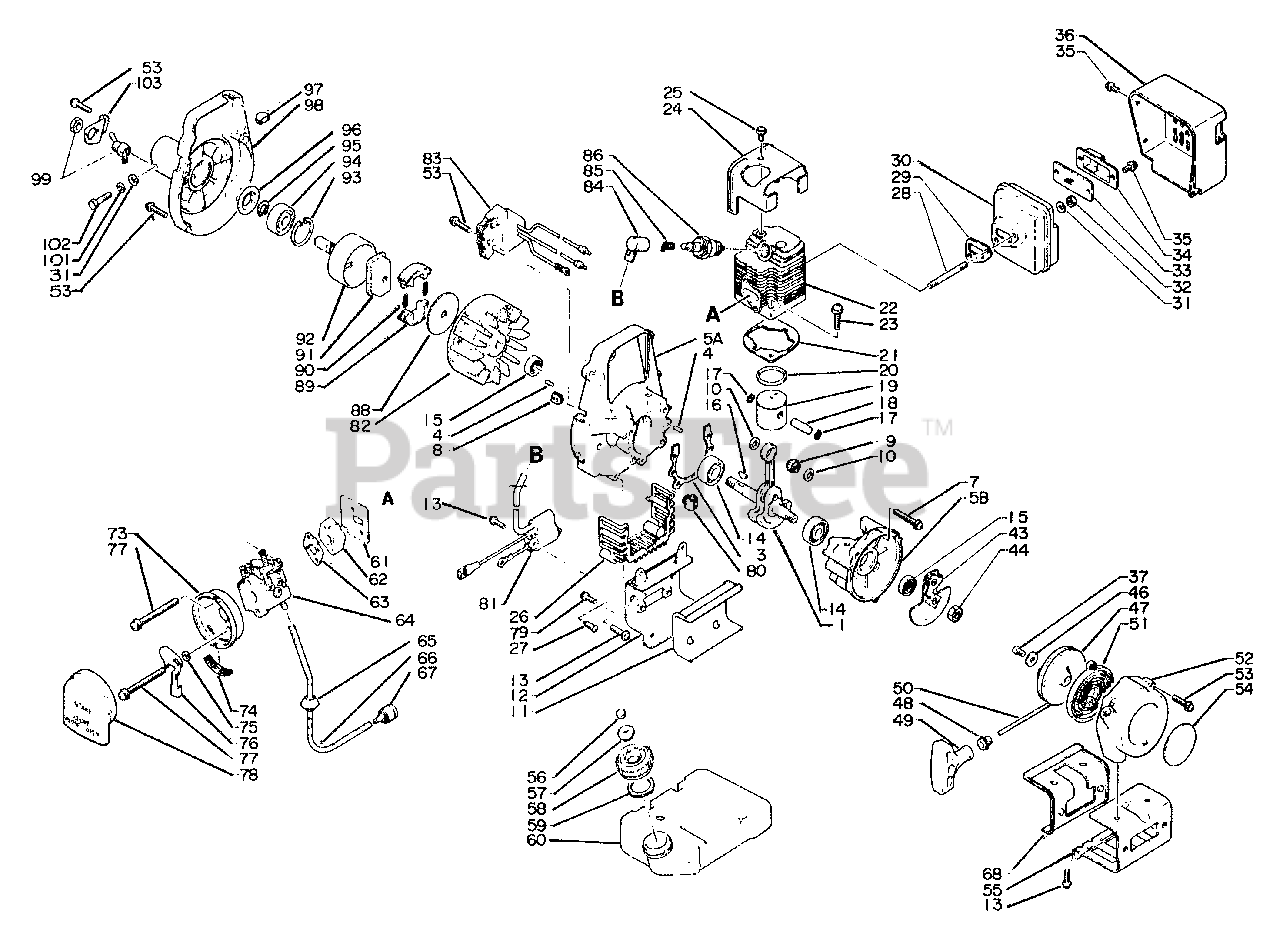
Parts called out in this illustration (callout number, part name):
1	CRANKSHAFT ASSY
3	GASKET, CRANKCASE
4	PIN - LOCATING
5	CRANKCASE KIT
5A	CRANKCASE KIT
5B	CRANKCASE KIT
7	SCREW - 5X30
9	BEARING, NEEDLE - 8
10	SPACER, PISTON
11	CUSHION
12	BRACKET, FUEL TANK
13	SCREW - 4X14
14	BEARING, BALL - 6201
15	SEAL, OIL
17	RING, RETAINING
18	PIN, PISTON
19	PISTON
20	RING, PISTON
21	GASKET, CYLINDER
22	CYLINDER
23	SCREW - 6X20
24	COVER, ENGINE
25	SCREW - 5X10
26	SEAL, DUST
27	SCREW - 4X14 -- TAPPING
29	GASKET, EXHAUST
30	MUFFLER
31	WASHER - 5
32	LOCKNUT - 5
33	SCREEN, SPARK ARRESTOR
34	GUIDE, EXHAUST
35	SCREW - 4X10
36	COVER, MUFFLER
37	SCREW - 4X10
43	STARTER PAWL ASSY
44	STARTER ASSY
46	WASHER
47	REEL, ROPE
48	ROPE, STARTER - 3X850
49	GRIP, STARTER
50	GUIDE, ROPE
51	SPRING, REWIND
52	CASE, STARTER
53	SCREW - 4X20
54	LABEL - ECHO
55	BRACKET, FUEL TANK
58	CAP
59	GASKET, CAP
60	TANK, FUEL
61	GASKET, INTAKE
62	INSULATOR, INTAKE
63	GASKET, INTAKE
64	CARBURETOR WA-81
66	PIPE - 3X5X150 -- BLACK
67	FILTER, FUEL
68	CUSHION
73	CASE, AIR FILTER
75	WASHER - 5
76	SHUTTER, CHOKE
77	SCREW - 5X57
78	FILTER, AIR
79	SCREW - 4X12
80	CLAMP
81	COIL, IGNITION
82	FLYWHEEL
83	COIL, IGNITION
84	CAP, SPARK PLUG
85	TERMINAL, SPARK PLUG CAP
86	SPARK PLUG -- CJ-8
88	PLATE, CLUTCH
89	SHOE, CLUTCH
90	SPRING, CLUTCH
91	HUB, CLUTCH
92	DRUM, CLUTCH
93	RING, RETAINING - 32
94	BEARING, BALL - 6201
95	RING, RETAINING - 12
96	RETAINER, PIPE
97	PLUG
98	CASE, FAN
99	IGNITION SWITCH KIT
101	LOCKWASHER - 5
102	BOLT - 5X25
103	BRACKET, SWITCH
